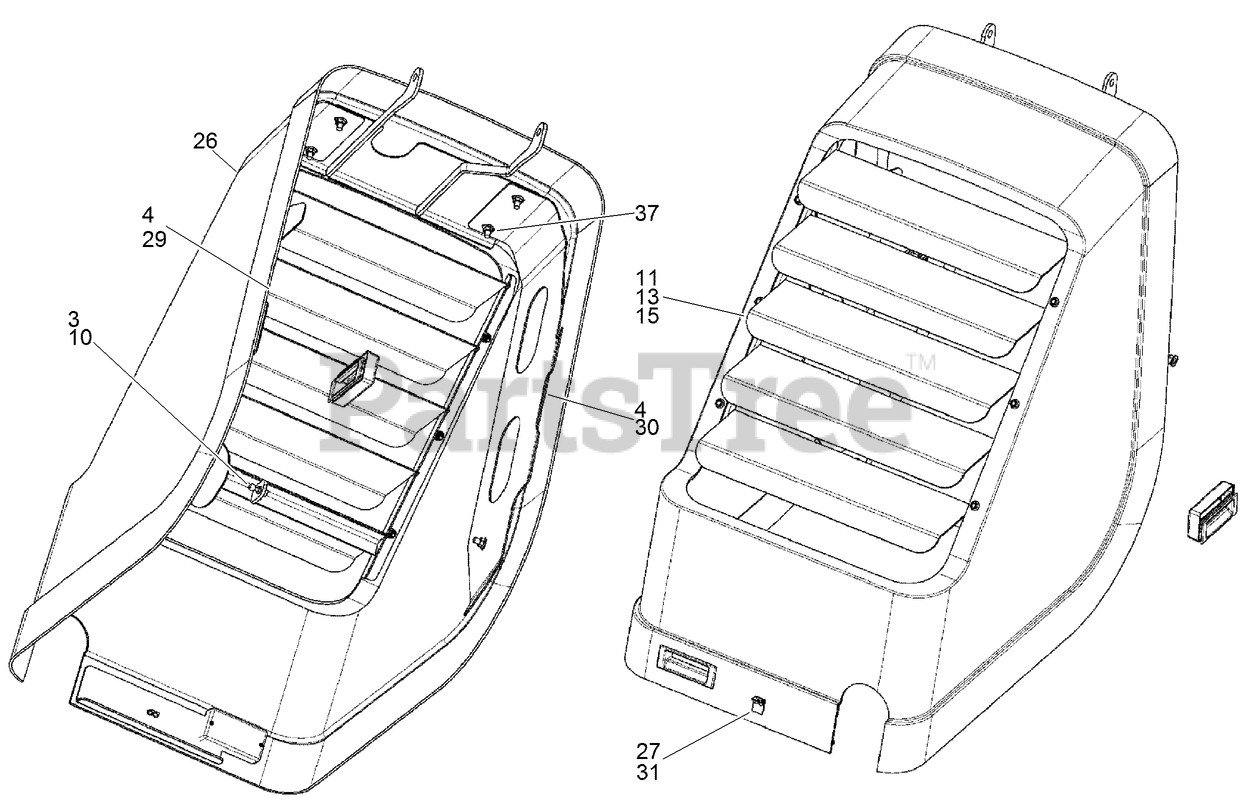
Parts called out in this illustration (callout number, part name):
3	NUT - Prev Trq 5/16 GRB ZND Direct
4	NUT-Serr Flg 3/8-16 UNC GR5 ZND
10	STUD-BALL
11	NUT-TORQUE, PREVAILING
13	SCREW-HH
15	ASSEMBLY - Louver
26	ASSEMBLY - Rear Hood
27	NUT-#10-24 KEPS
29	PLATE - Guide
30	PLATE - Guide
31	SCREW - Hex Hd #10 - 24 x 0.875 CST PHC
37	ASSEMBLY - Rear Hood Mount
